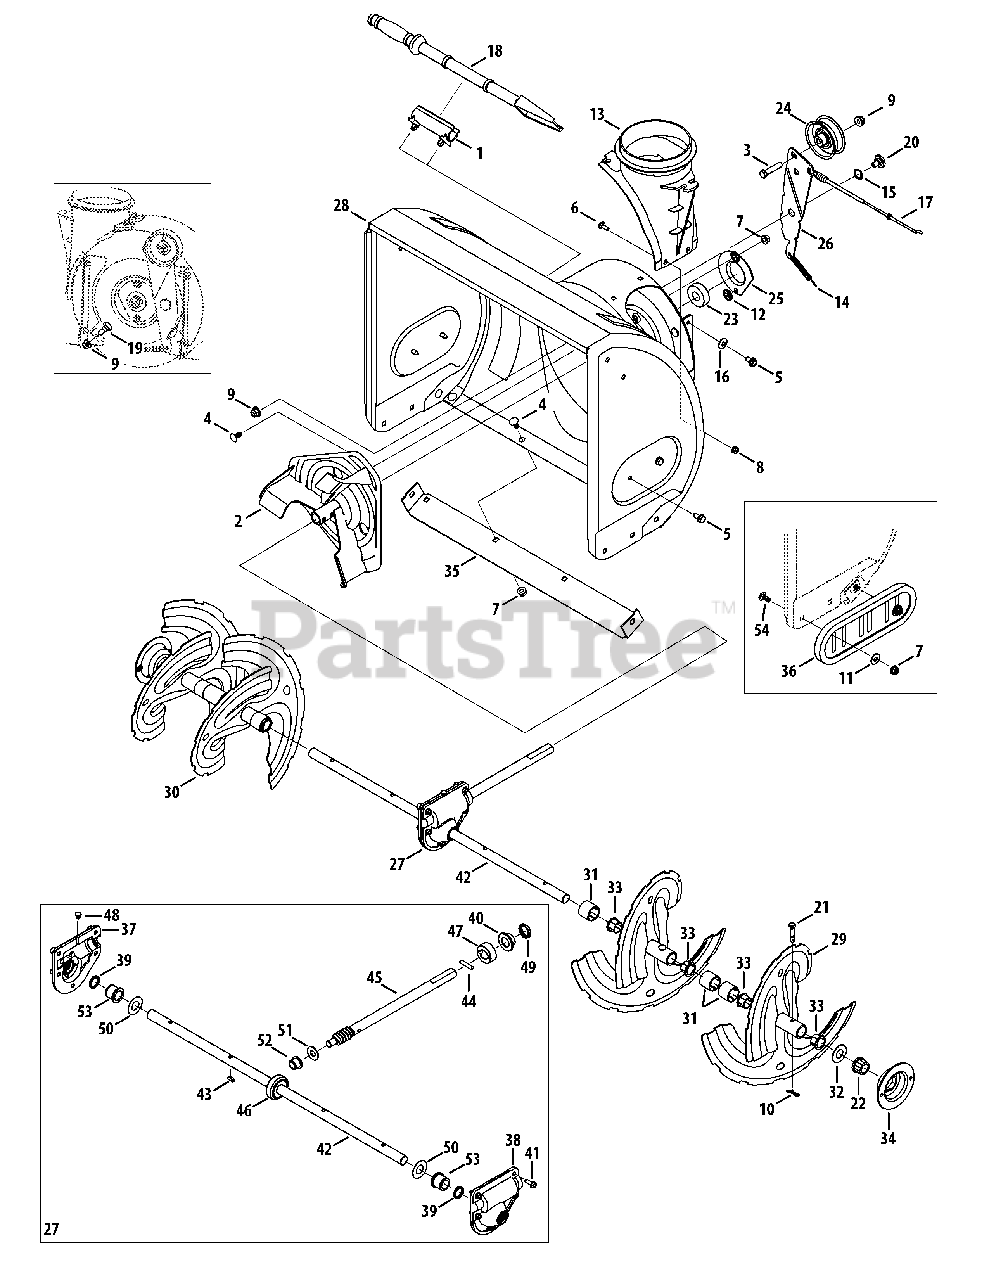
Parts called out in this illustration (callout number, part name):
1	Snow Removal Tool Mount
2	Impeller Assembly, 12" Dia.
3	Hex Screw, 3/8-16, 1.75, Gr5
4	Bolt, Carriage, 5/16-18, .750 Gr1
5	Screw, 5/16-18, 0.750
6	Screw, Carriage, 1/4-20, .750, Gr5
7	Nut, Flange Lock, 5/16-18, Nylon
8	Nut, Flange Lock, 1/4-20, Nylon
9	Nut, Flange Lock, 3/8-16, Nylon
10	Cotter Pin, Bow-tie
11	Washer, Flat, .349 x .879 x .063
12	Nut, Push-on, .25 Dia
13	Chute, Adapter 5" Dia
14	Spring, Extension, .38 OD x 4.59
15	Washer, Wave, .625 x .885 x .015
16	Washer, Bell, .340 x .872 x .060
17	Clutch Cable, Auger, 47.23"
18	Snow Removal Tool
19	Screw, Shoulder, .498 x .34, 3/8-16
20	Screw, Shoulder, .625 x .17, 3/8-16
21	Shear Pin, .25 x 1.50
22	Bearing, Hex Flange x .75 ID
23	Bearing, Ball, .75 ID x 1.85 OD
24	Flat Pulley, Idler, 2.75 OD
25	Housing, Bearing, 1.85 ID
26	Bracket, Auger Idler w/ Brake
27	Gearbox Assembly, Auger, 26"
28	Housing Assembly, Auger 26"
29	Spiral Assembly, LH
30	Spiral Assembly, RH
31	Spacer, 1.25 OD x .75 ID x 1.00
32	Washer, Flat, .76 x 1.49 x .06
33	Bushing, Flange, .80 ID x .91 OD
34	Housing, 1" Hex Bearing
35	Shave Plate, 2.25 x 25.66
36	Slide Shoe, Polymer
36	Slide Shoe Kit
37	Housing, Auger, RH Reduced
38	Housing, Auger, LH Reduced
39	Seal, Oil, .750 x 1.00 x .125
40	Bearing, Flange, .75 x 1.0 x .59
41	Screw, Self-tapping, 1/4-20, 0.750
42	Axle, Auger, 26"
43	Key, Hi-pro 3/16 x 5/8
44	Pin, Dowel, .25 OD x 1.2
45	Shaft, Worm .75 OD
46	Gear, Worm 20T
47	Collar, Thrust
48	Plug, 1/4 x .437
49	Seal, Oil, .75 x 1 x .131
50	Washer, Flat, .760 ID x 1.5 OD
51	Washer, Flat, .51 x 1.12
52	Bearing, Flange, .75 x 1.0 x .925
53	Bearing, Flange, .75 x 1.00 x .975
54	Screw, Carriage, 5/16-18 x 1.00
